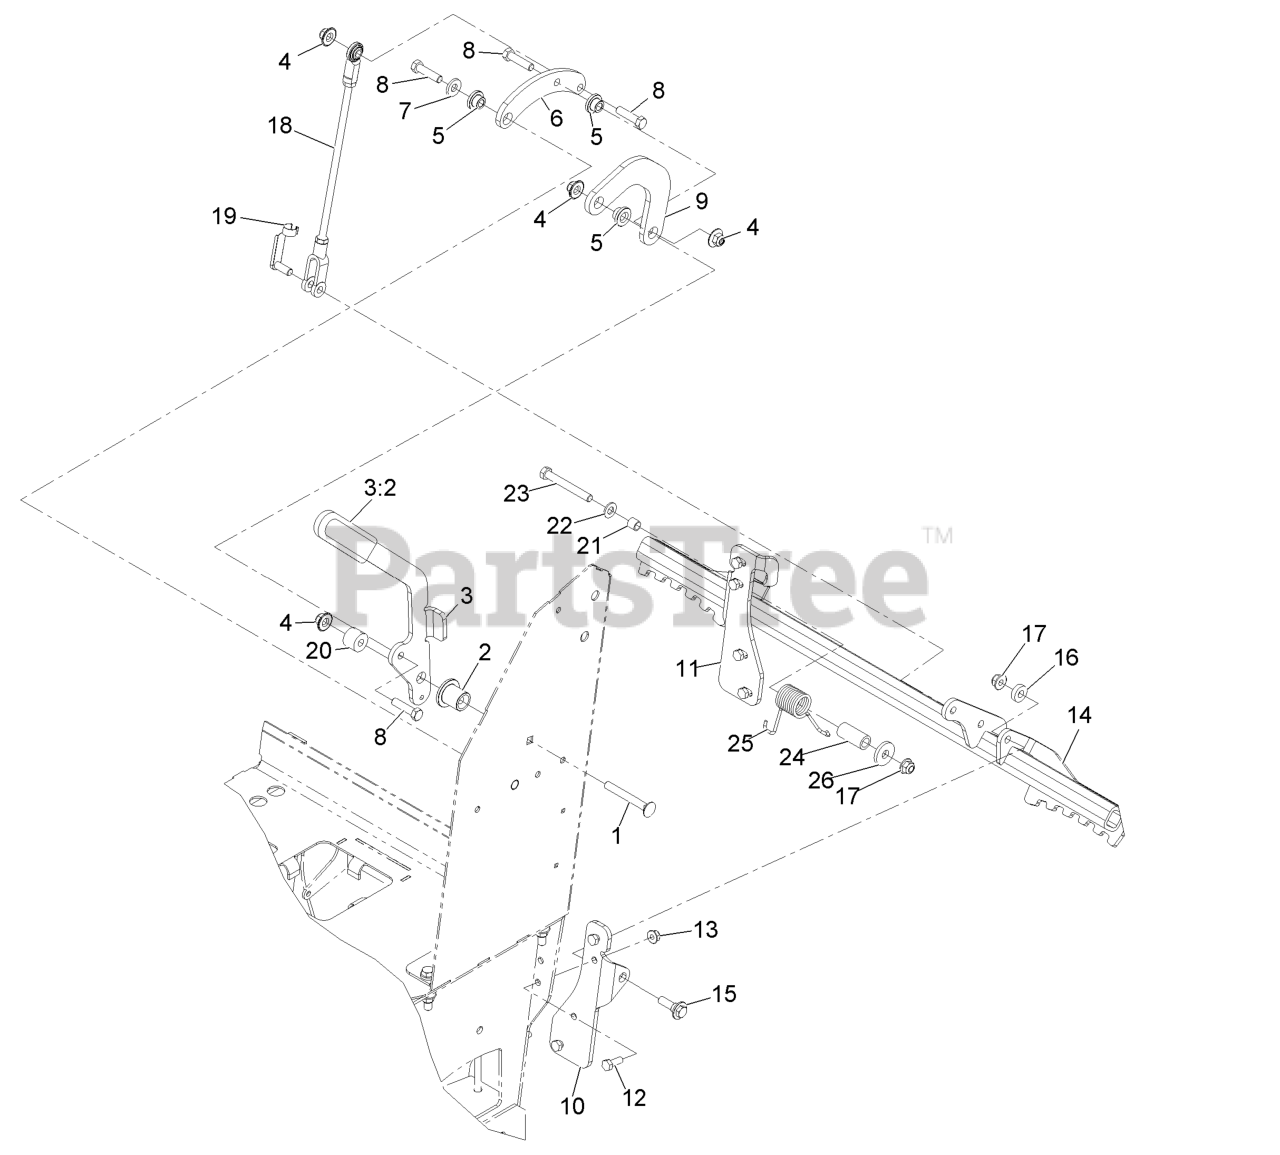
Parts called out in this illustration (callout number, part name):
1	SCREW-CARR
2	BUSHING-HANDLE
3	HANDLE-W/GRIP ASM
3:2	GRIP-LEVER
4	Nut-Nyloc 3/8-16 Flg
5	BUSHING-FLANGED
6	ARM-BRAKE BELLCRANK
7	WASHER-BELLEVILLE
8	SCREW-HH
9	LINK-BRAKE HANDLE
10	BRACKET-BRAKE MOUNT, LH
11	BRACKET-BRAKE MOUNT, RH
12	SCREW-HH
13	NUT-HF, NI
14	BAR-BRAKE
15	SCREW-SHOULDER, HWH
16	SPACER
17	NUT-HF, NI
18	ASM-BRAKE LINKAGE
19	PIN-SPRING, CLEVIS
22	WASHER-FLAT
23	SCREW-CARR
25	SPRING-TORSION
